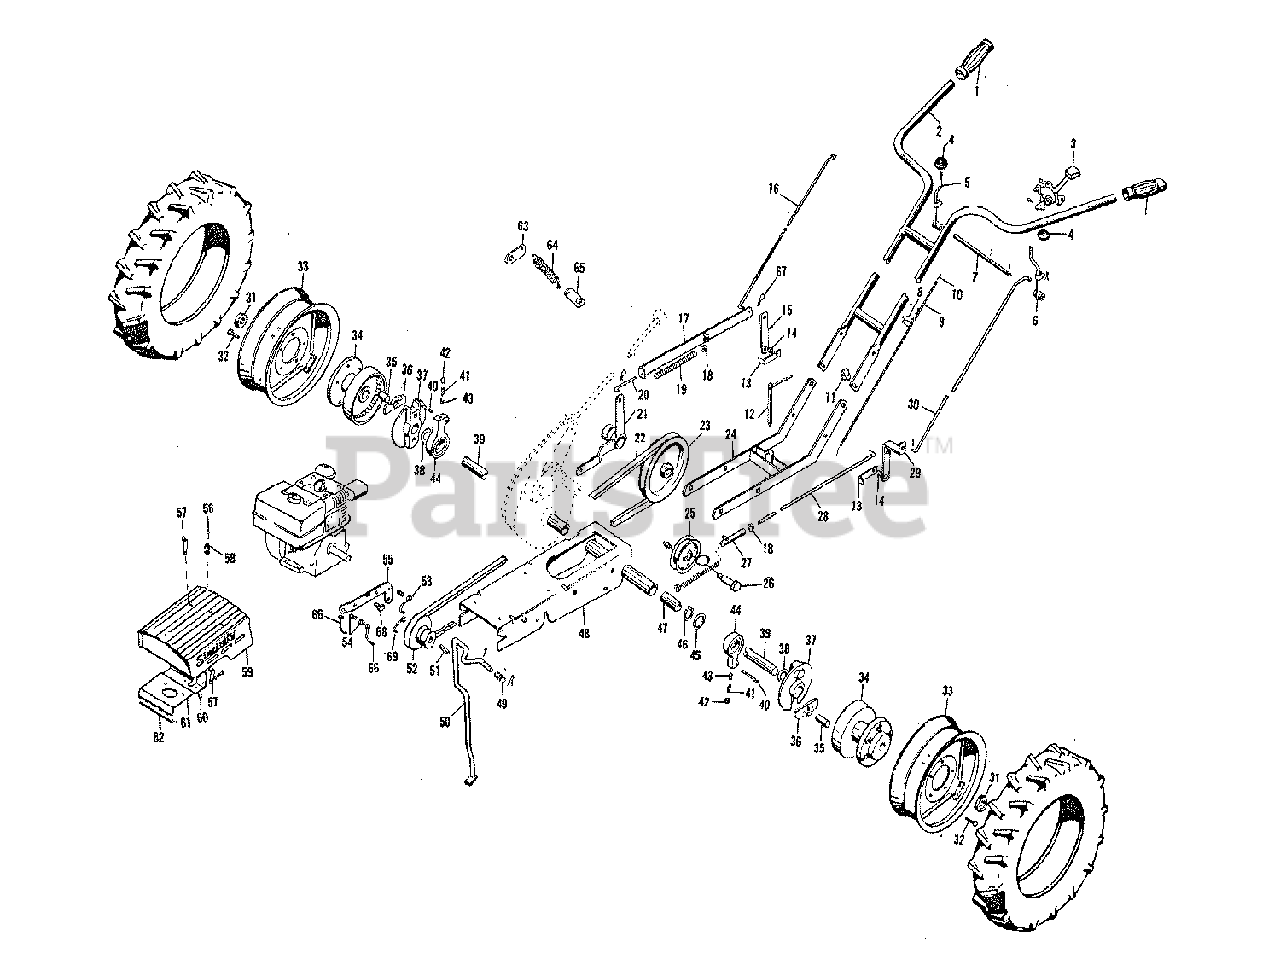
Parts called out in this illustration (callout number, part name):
1	HANDLE GRIP
2	HANDLE ASSEMBLY
3	THROTTLE CONTROL LEVER ASSEMBLY
4	CLUTCH LEVER BALL
5	R.H. CLUTCH LEVER ASSEMBLY
6	L.H. CLUTCH LEVER ASSEMBLY
7	LEVER SHAFT
8	CABLE CLIP
9	THROTTLE WIRE HOUSING
10	THROTTLE CONTROL WIRE
11	THROTTLE WIRE HOUSING CLAMP
12	HITCH PIN ASSEMBLY
13	LEVER STOP
15	LOWER CLUTCH PIVOT LEVER
16	UPPER IDLER CLUTCH ROD
17	IDLER CLUTCH ROD GUIDE ASSEMBLY
18	IDLER ROD SET COLLAR
19	SPRING IDLER ROD
20	LOWER IDLER CLUTCH ROD
21	IDLER LEVER ASSEMBLY
22	46" "V" BELT
23	TRANSMISSION PULLEY
24	FRAME ASSEMBLY
25	IDLER PULLEY ASSEMBLY
26	IDLER PULLEY PIN
27	ROD SOCKET ASSEMBLY
28	LOWER IDLER ROD
29	LOWER CLUTCH LEVER
30	UPPER IDLER ROD
31	SET COLLAR
33	DRIVE WHEELS (6-12 Tires)
34	WHEEL HUB
35	RATCHET PAWL PIN
36	RATCHET PAWL ASSEMBLY
37	RATCHET CAGE
40	RATCHET PAWL TRIP FINGER
41	TRIP FINGER HOLDER SPRING
42	7/16-14 x 1/2" HEADLESS
43	TRIP FINGER HOLDER SPRING
44	HOLDER WITH BEARING ASSEMBLED
45	AXLE HOUSING SPACER
46	RETAINING RING
47	AXLE BEARING
48	BASE ASSEMBLY
49	STAND SPRING
50	STAND ASSEMBLY
51	KEY FOR ENGINE PULLEY
52	ENGINE PULLEY KEY
53	BELT STOP
55	BELT STOP HOLDER
56	PIN - Hood
58	SPRING - Hood
59	HOOD ASSEMBLY
60	1/4-20 LOCKNUT
61	BRACKET ASSEMBLY - Hood
62	PIN- Hinge
63	HOLDER, Spring Upper
65	HOLDER, Spring Lower
66	BELT STOP
67	SPRING CLIP
68	HOLDER SCREW
69	BELT STOP
